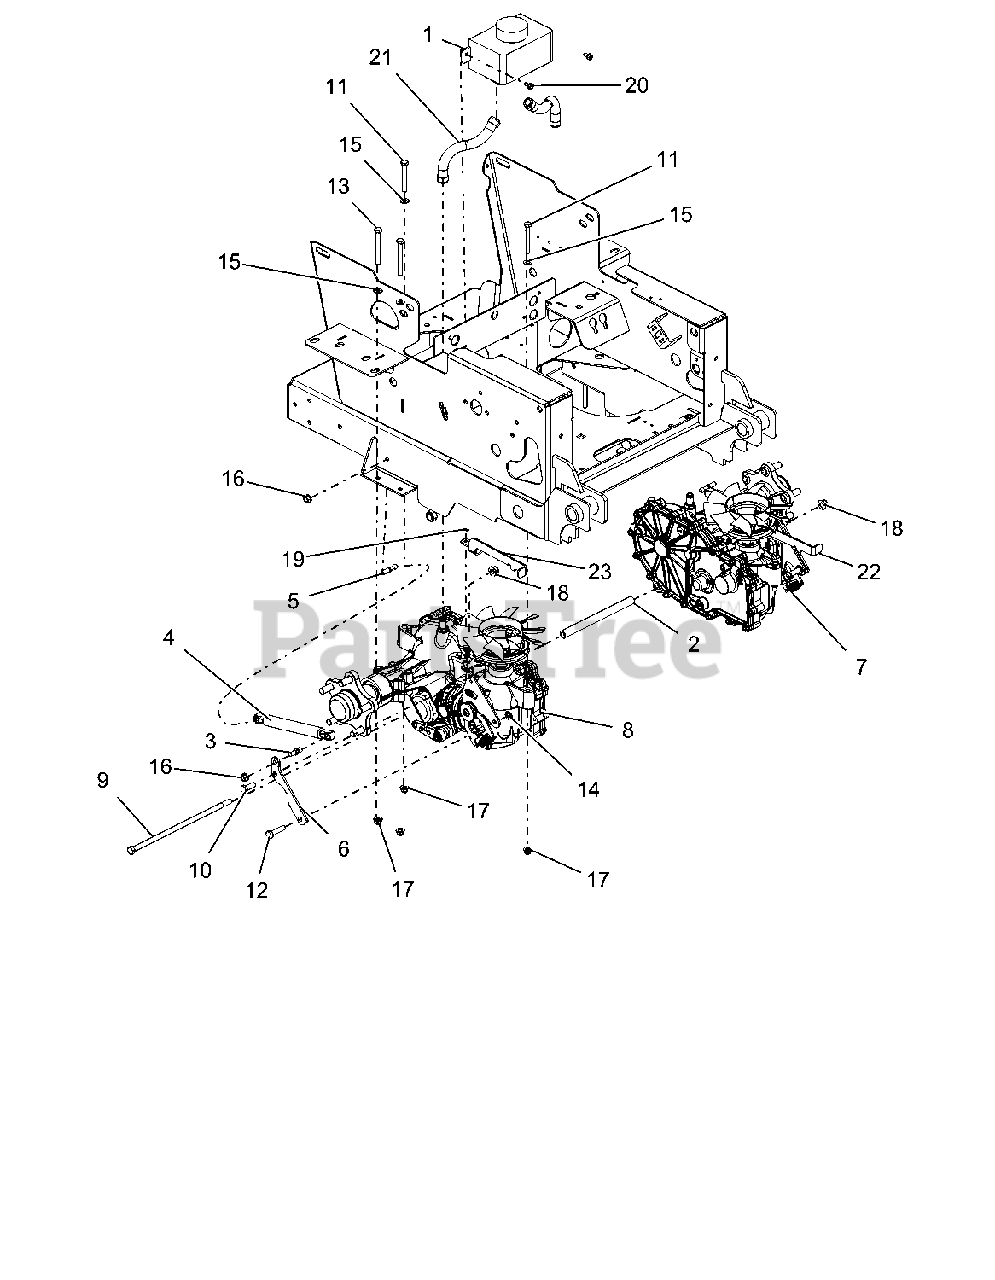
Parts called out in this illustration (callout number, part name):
1	TANK, EXPANSION
2	SPACER, .406 ID X .630 OD X 7.724
3	STUD-BALL
4	DAMPER,
5	STUD, BALL THREADED
6	TRANSMISSION DAMPER MTG PLATE - BLK
7	TRANSAXLE, ZT3100 - LH
8	TRANSAXLE, ZT3100 - RH
9	BLT, HEX .38-16X11.00 GR5 YWZC
10	BLT-HEX .38-16X1.00 GR5 YWZC
11	BLT-HEX .31-18X2.50 GR5 YWZC
12	BLT-HEX .38-16X1.50 GR5 YWZC
13	BLT-HEX .31-18X3.00 GR5 YWZC
14	WSHR-LK .38X.094 REG YWZC
15	WSHR-FL-STL.344X.688X.065YWZC
16	NUT, LK-TOP-FLG .312-18 YWZC
17	NUT-LK-NYL-FLG .31-18 YWZC
18	NUT-LK-NYL-FLG .38-16 YWZC
19	PIN-HAIR INT .06X.18X.77
20	SCR-TAP .25-20X.50 HWH TR YWZ
21	HYDRO OVERFLOW TANK HOSE
22	RH, DUMP VALVE LEVER
23	LH, DUMP VALVE LEVER
